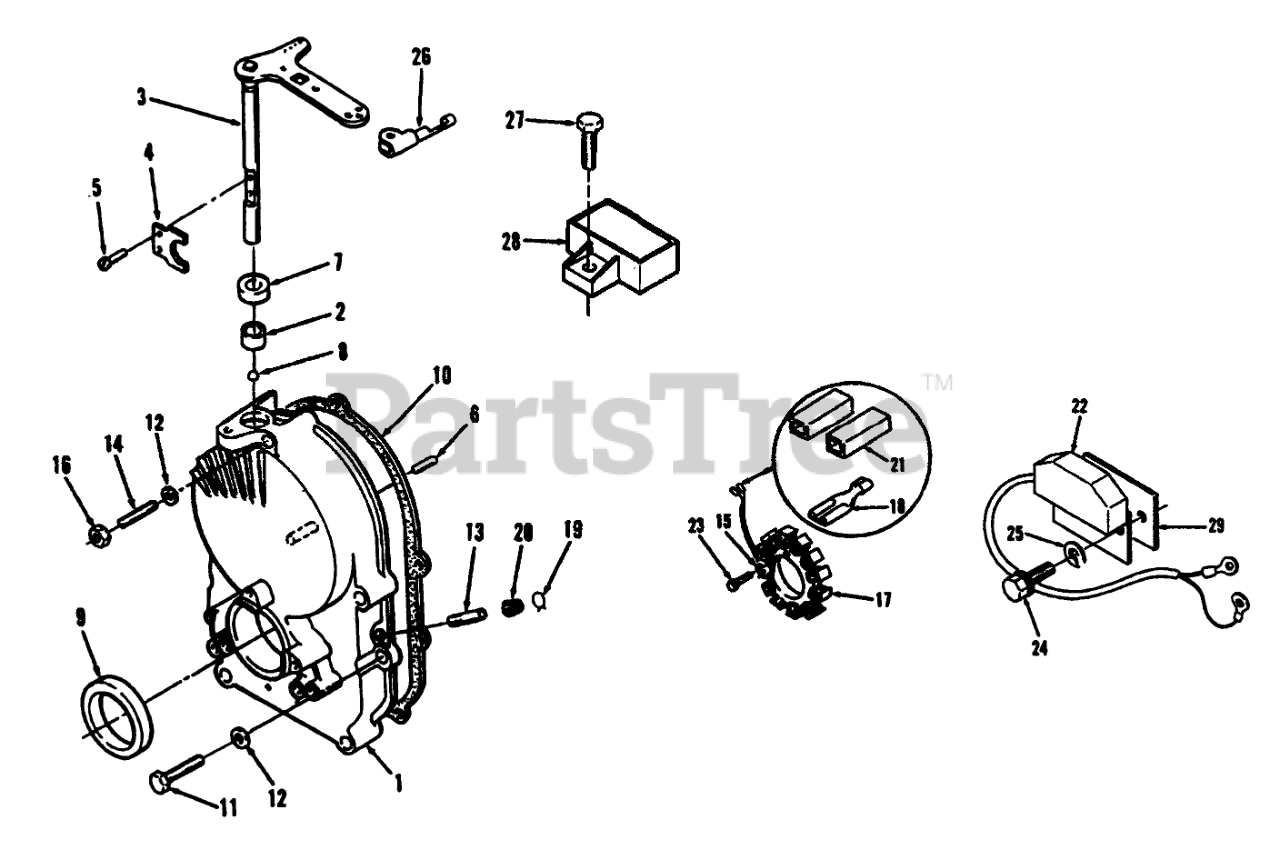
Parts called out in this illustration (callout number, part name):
1	GEAR-CASE KIT
2	Bearing
3	SHAFT AND ARM
4	YOKE
5	Screw
6	Washer
7	SEAL
8	BALL
9	SEAL
10	Gasket
11	Bolt
12	WASHER
13	Vacuum Tube
14	Stud
15	Washer-Lock
16	Nut
17	Stator (Includes Terminals)
18	Stator Leads Terminal
19	CLAMP
20	CAP-FUEL OUTLET
21	Body-Terminal Connector Kit (Includes Terminals)
22	Control-Ignition
23	Screw-HH
24	Bolt
25	WASHER-LOCK
27	SCREW-HWH
28	Regulator
29	Insulator
